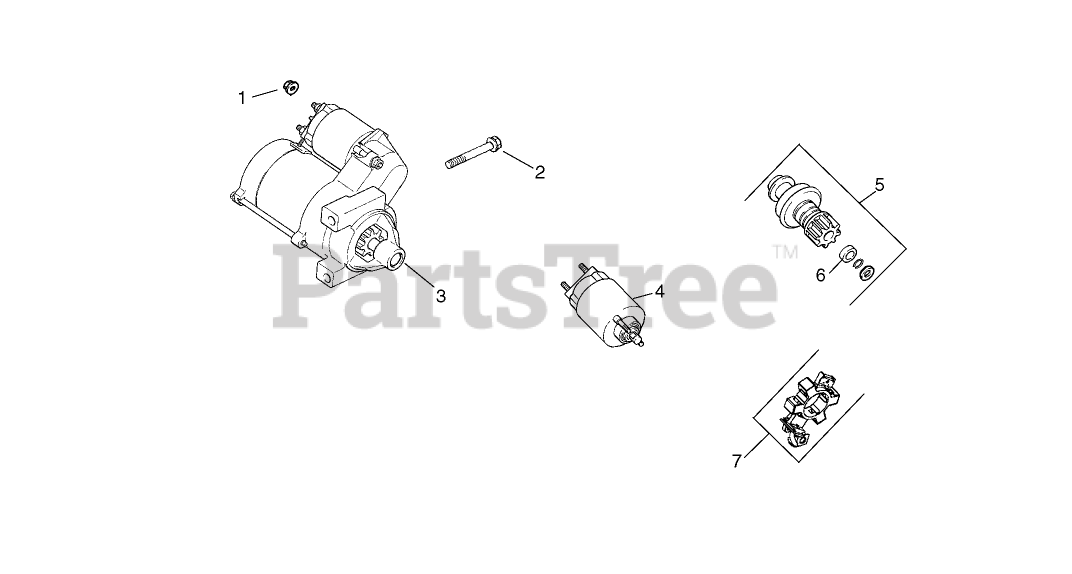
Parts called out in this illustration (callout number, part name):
1	NUT-FLANGE (M8X1.25)
2	SCREW-FLG (M8X1.25X80)
3	Starter, solenoid shift assembly (Includes 4-7)
4	Solenoid Kit
5	Kit, pinion drive (Includes 6)
6	RING-RETAINING
7	BRUSH HOLDER KIT
